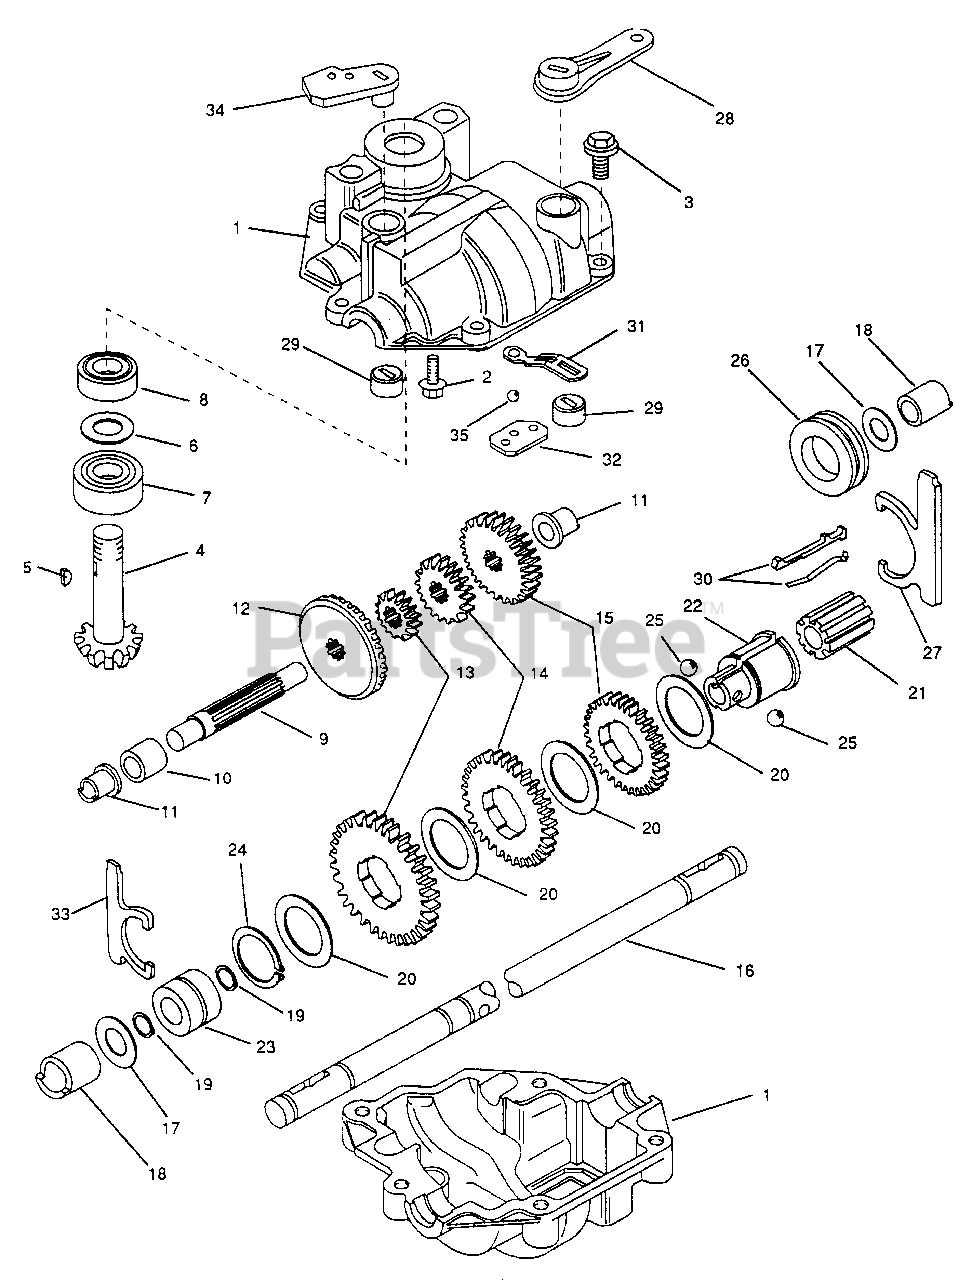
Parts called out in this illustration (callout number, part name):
1	Upper & Lower Case Kit
2	Tapping Screw
3	Tapping Screw
4	Shaft-Input
5	Woodruff Key
7	Bearing-Lower
8	Bearing-Upper
9	Shaft, Reduction Kit (Inc. 10 & 11)
11	Bushing Set
12	Ring Gear
13	Gear Set
14	Gear Set
15	Gear Set
16	Axle Shaft Kit (Inc. 17-19)
18	Bushing Set
19	Snap Ring
21	Holder, Key
22	Collar, Shift
24	Snap Ring
25	Ball
26	Collar, Sliding
27	Fork, Shift
28	Arm, Shift
29	Support, Fork
30	Spring & Key, Shift
33	Fork, Clutch
34	Arm, Clutch
